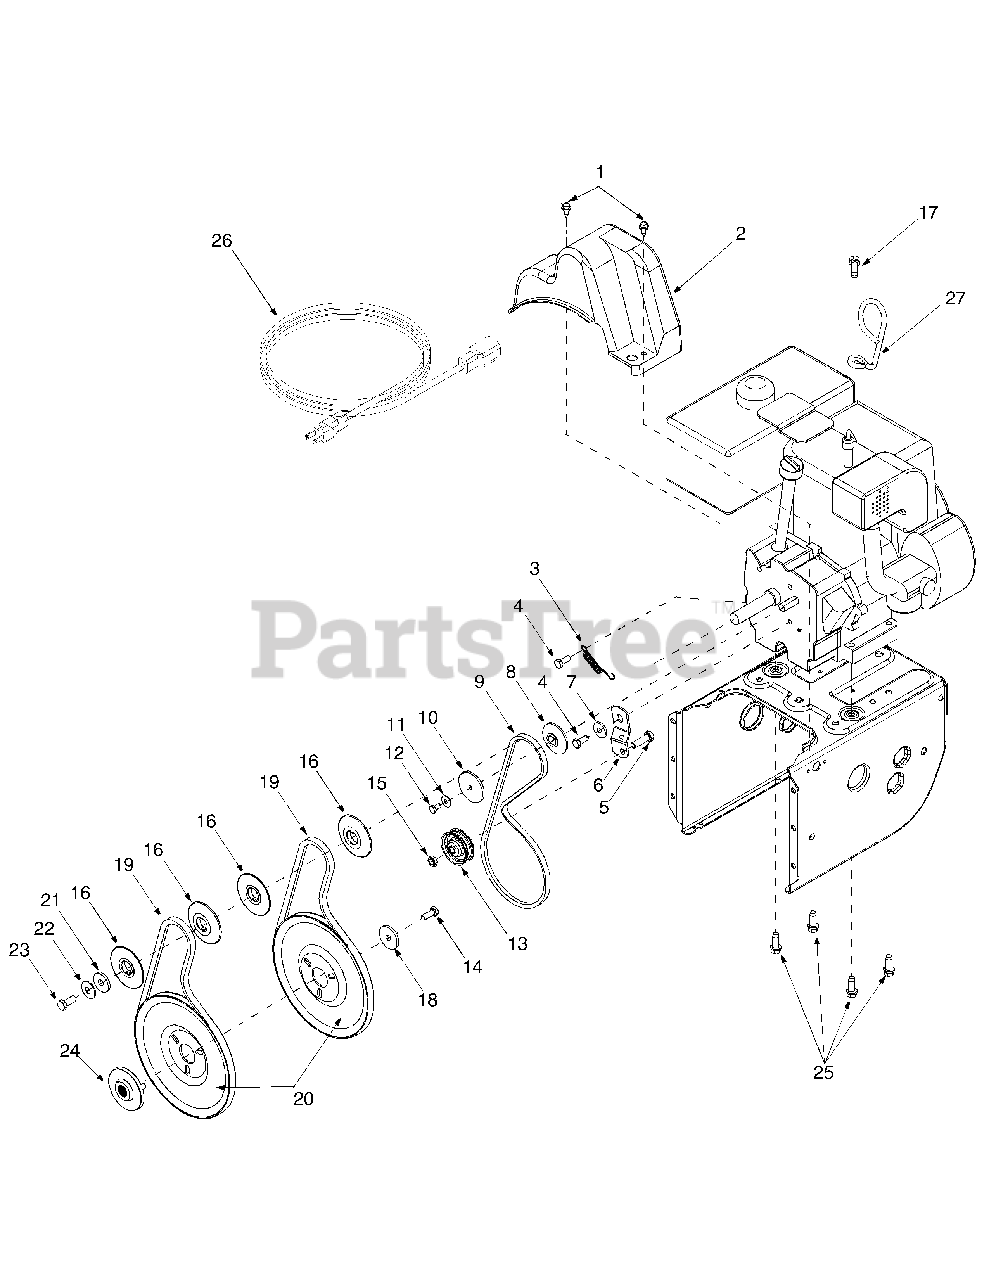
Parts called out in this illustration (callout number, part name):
1	Hex Washer Screw 1/4-20 x.625
2	Belt Cover
3	Extension Spring
4	Hex Screw 5/16-24 x.75
5	Hex Cap Screw 3/8-16 x 1.25
8	Pulley Half
9	V-Belt
10	Pulley Half
11	Bell Washer
12	Hex Cap Screw 1/4-28 x.50
13	Flat Idler
14	Lock Hex Cap Screw 5/16-24
15	Lock Jam Nut 3/8-16
16	Pulley Half
17	Self Tapping Screw, 5/16-18 x 1.00
18	Flat Washer
19	Belt
20	Auger Pulley
21	Flat Washer 3/8 x 1.25 OD
22	Bell Washer
23	Hex Cap Screw 3/8-24
24	Adapter Pulley
25	Hex Screw 3/8-16 x 1.0
26	Extension Cord
27	Cable Control Wire
